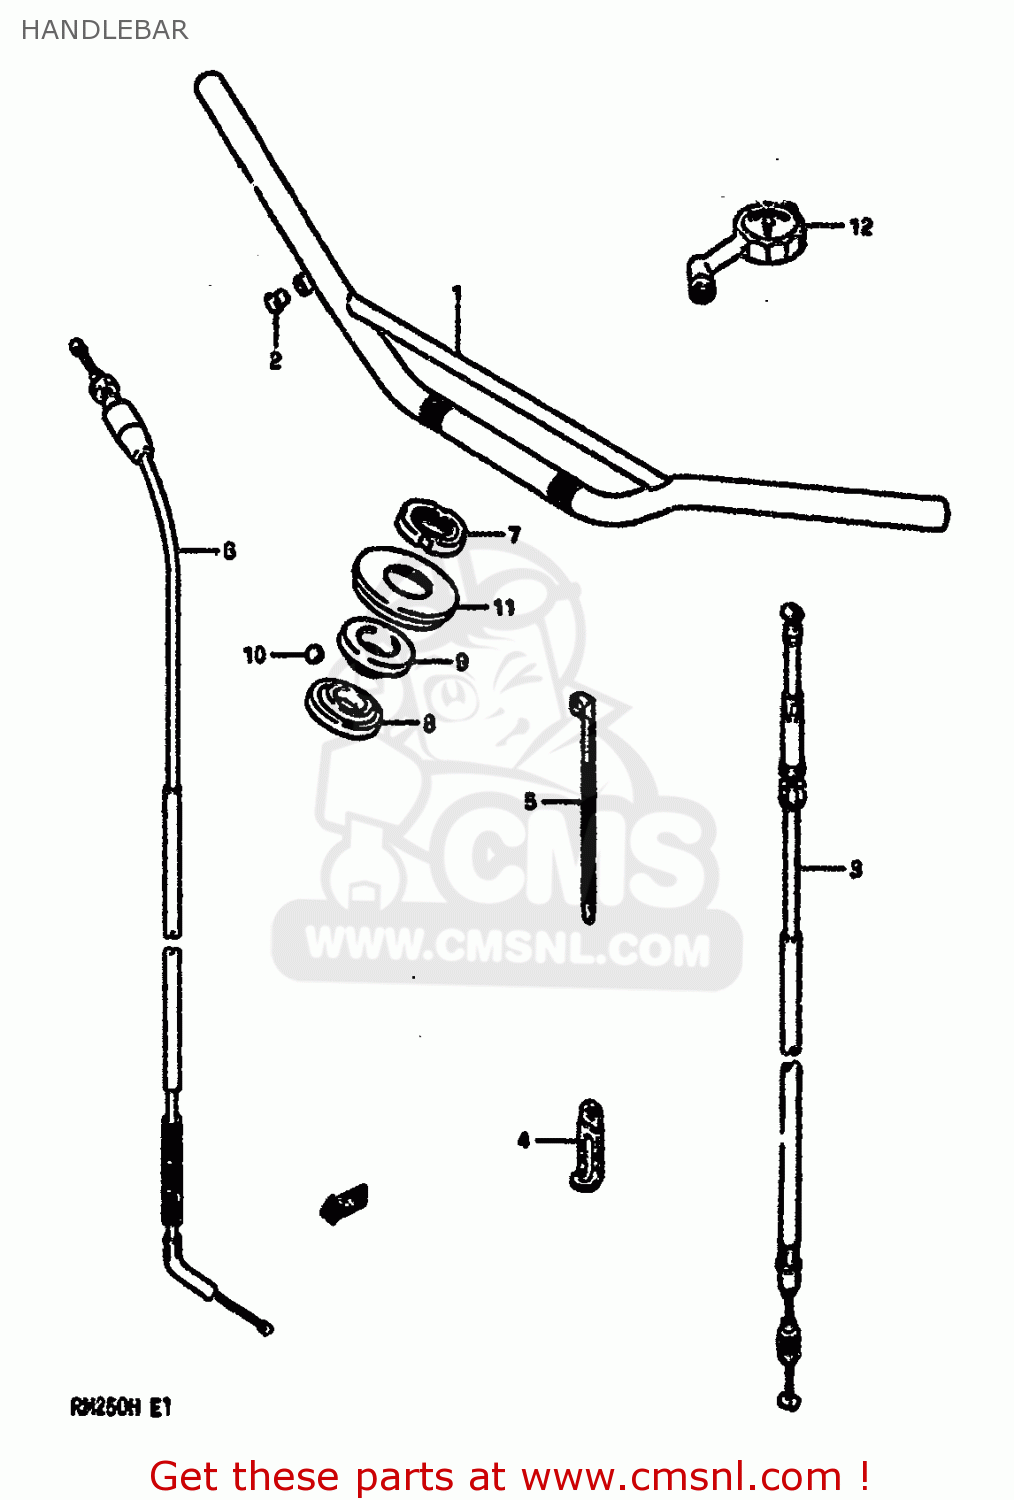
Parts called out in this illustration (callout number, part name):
1	HANDLEBAR
2	CAP(OD:14)
3	CABLE ASSEMBLY,CLUTCH
4	CLAMP L:35
5	CLAMP(L:145)
6	CABLE ASSEMBLY,THROTTLE
7	NUT,STEERING STEM
8	RACE,STEERING,INNER,UPPER
9	RACE,STEERING,OUTER,UPPER
10	BALL
11	SEAL,STEERING UPR DUST
12	GAUGE ASSY,AIR PRESSURE
